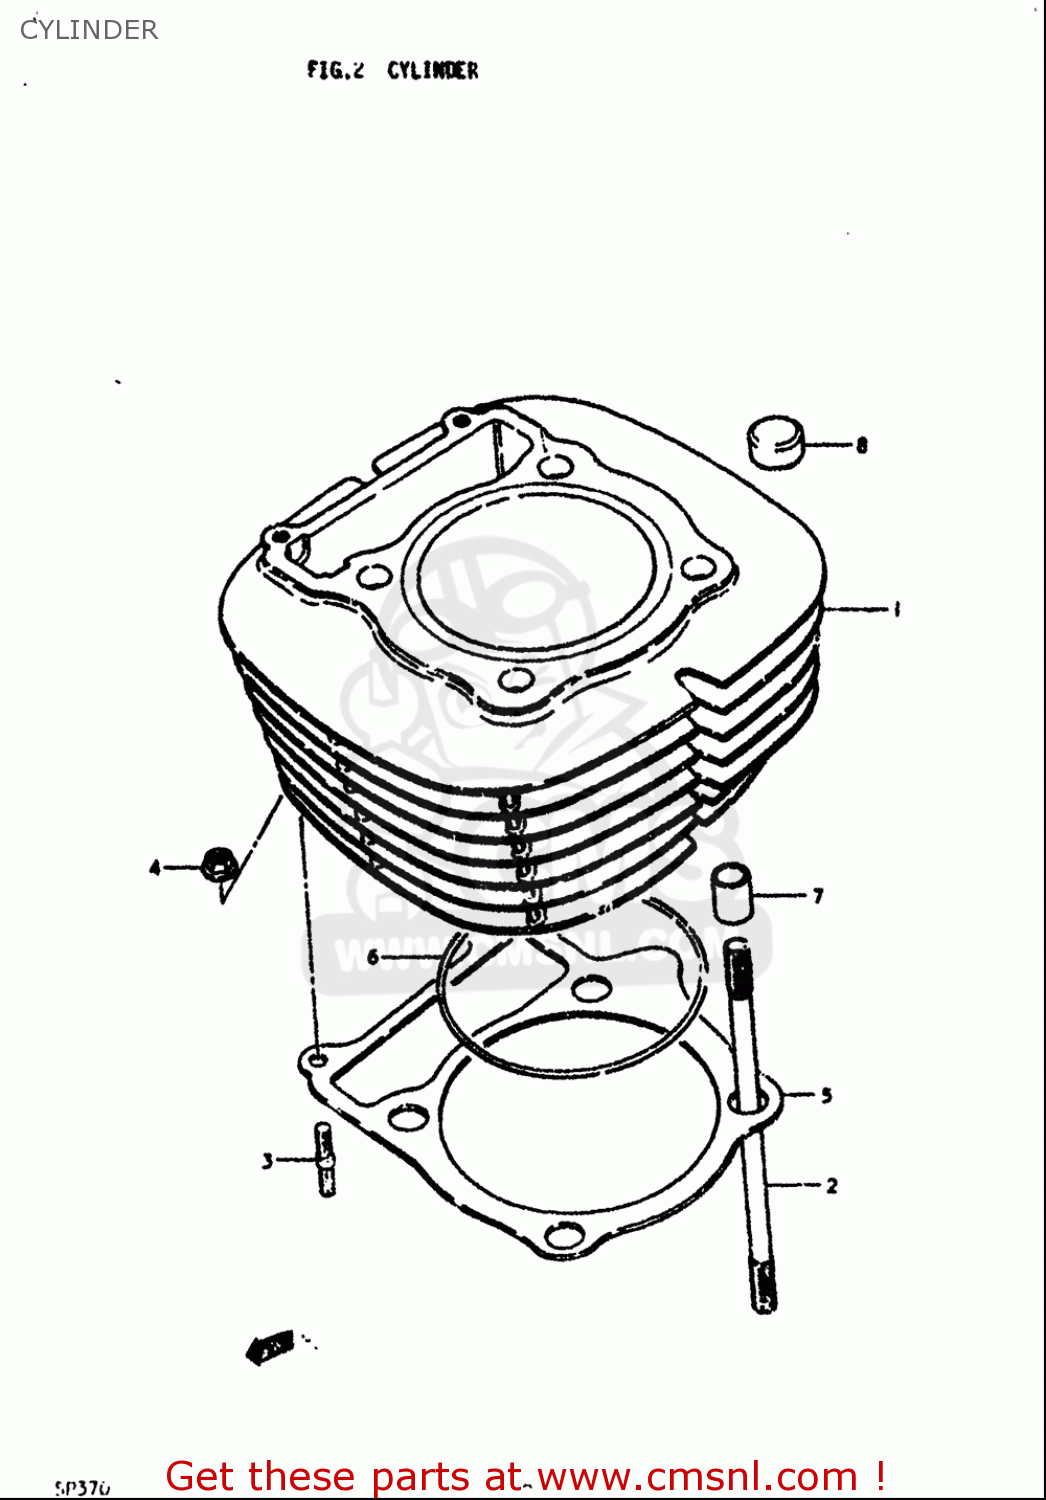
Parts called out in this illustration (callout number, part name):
2	BOLT,STUD
3	BOLT,STUD
4	NUT
5	GASKET,CYLINDER (NAS)
6	O RING(D:2,ID:87)
7	PIN
8	PAD,CYLINDER HEAD
